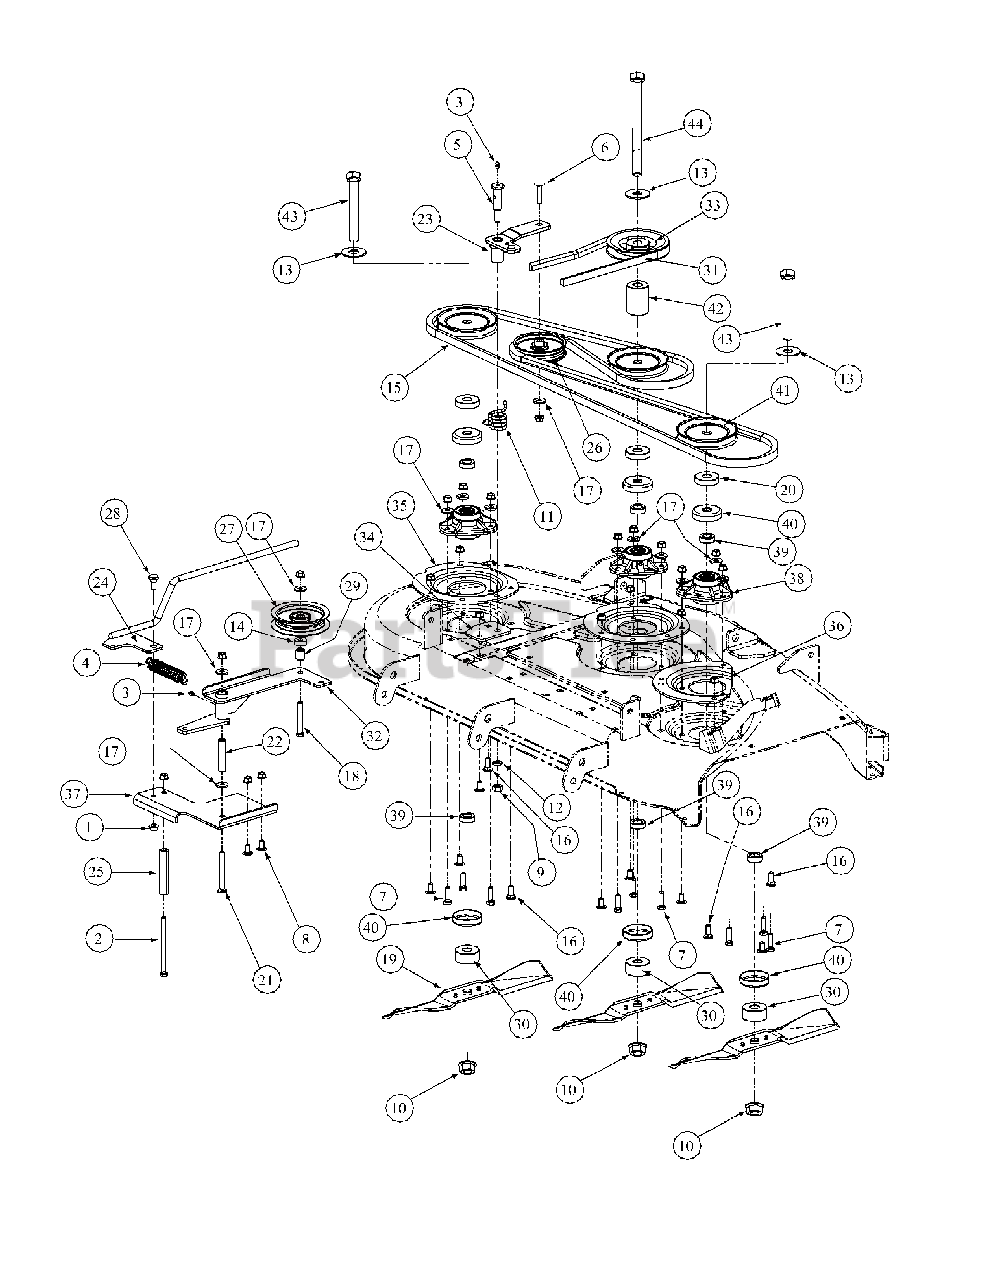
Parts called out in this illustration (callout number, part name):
1	Flange Lock Hex Nut, 3/8-16
2	Hex Capscrew, 3/8-16, 3.75
3	Grease Fitting, 1/4-28 x 3/16
4	Extension Spring, 1.0 OD x 5.125
5	Shoulder Screw, 7/16-14
6	Hex Carriage Screw, 3/8-16, 1.75
7	Hex Cap Screw, 3/8-16, 1.25
8	Carriage Bolt, 3/8-16 x .75 Lg
9	Hex Nut, 7/16-14
10	Flange Hex Nut, 3/4-16
11	Torsion Idler Spring
12	Lock Washer, 7/16
13	Flat Washer, .781 ID, 2.00 OD. 105
14	Spacer, .406 ID x 1.00 OD x .38
15	Belt, A Section x 107.3
16	Carriage Bolt, 3/8-16 x 1
17	Flat Washer, .406 ID, 1.0 OD, .105
18	Hex Capscrew, 3/8-16, 2.75
19	Mower Blade, 16.5 Lg
20	Spacer, .76ID x 2.0OD x .477
21	Carriage Bolt, 3/8-16 x 3.5 Lg
22	Spacer, .39 ID x .625 OD x 2.75
23	Idler Arm Assembly, Bearing
24	Idler Spring Rod Assembly
25	Spacer, .405 x .75 x 3.875
26	Flat Pulley with Flanges
27	Idler Pulley, 4.06 OD with Deep Flange
28	Shoulder Screw, .50 x .27 Lg; 3/8-16
29	Spacer, .385 ID x .75 OD x .875
30	Spacer, .760 ID x 2.000 OD x 0.9
31	Belt, B Section x 83.2
32	Idler Arm Assembly, Flat Top Bearing
33	Cast Pulley, 5.25 OD
34	48" Idler Arm Mounting Plate
35	Disk Reinforcement
36	Disk Reinforcement, Right Hand
37	48" Idler Arm Mounting Bracket
38	Bearing Housing Assembly
39	Spacer, .76ID x 1.25 OD x .44 Lg
40	Spindle Cup
41	Pulley, A Sect x 4.90
42	Spacer, .765 ID x 1.75 OD x 2.42
43	Hex Capscrew, 3/4-16, 5.50
44	Hex Capscrew, 3/4-16, 8.50
